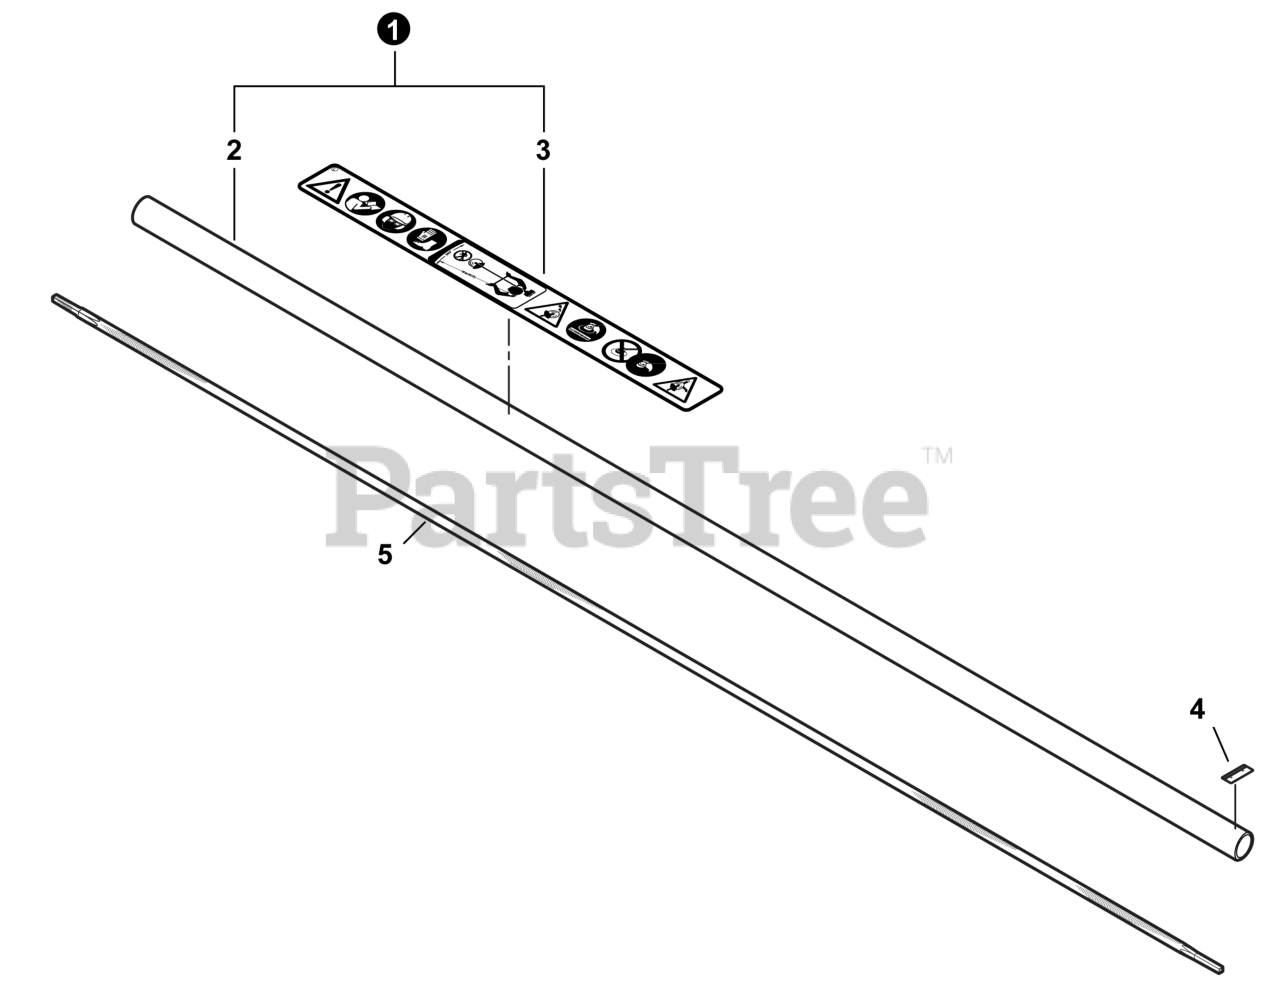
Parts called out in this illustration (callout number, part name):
1	MAIN PIPE ASSY
2	MAIN PIPE ASSY 25x1500
3	LABEL - CAUTION - ISO
4	LABEL - ALIGNMENT
5	DRIVESHAFT - FLEXIBLE
